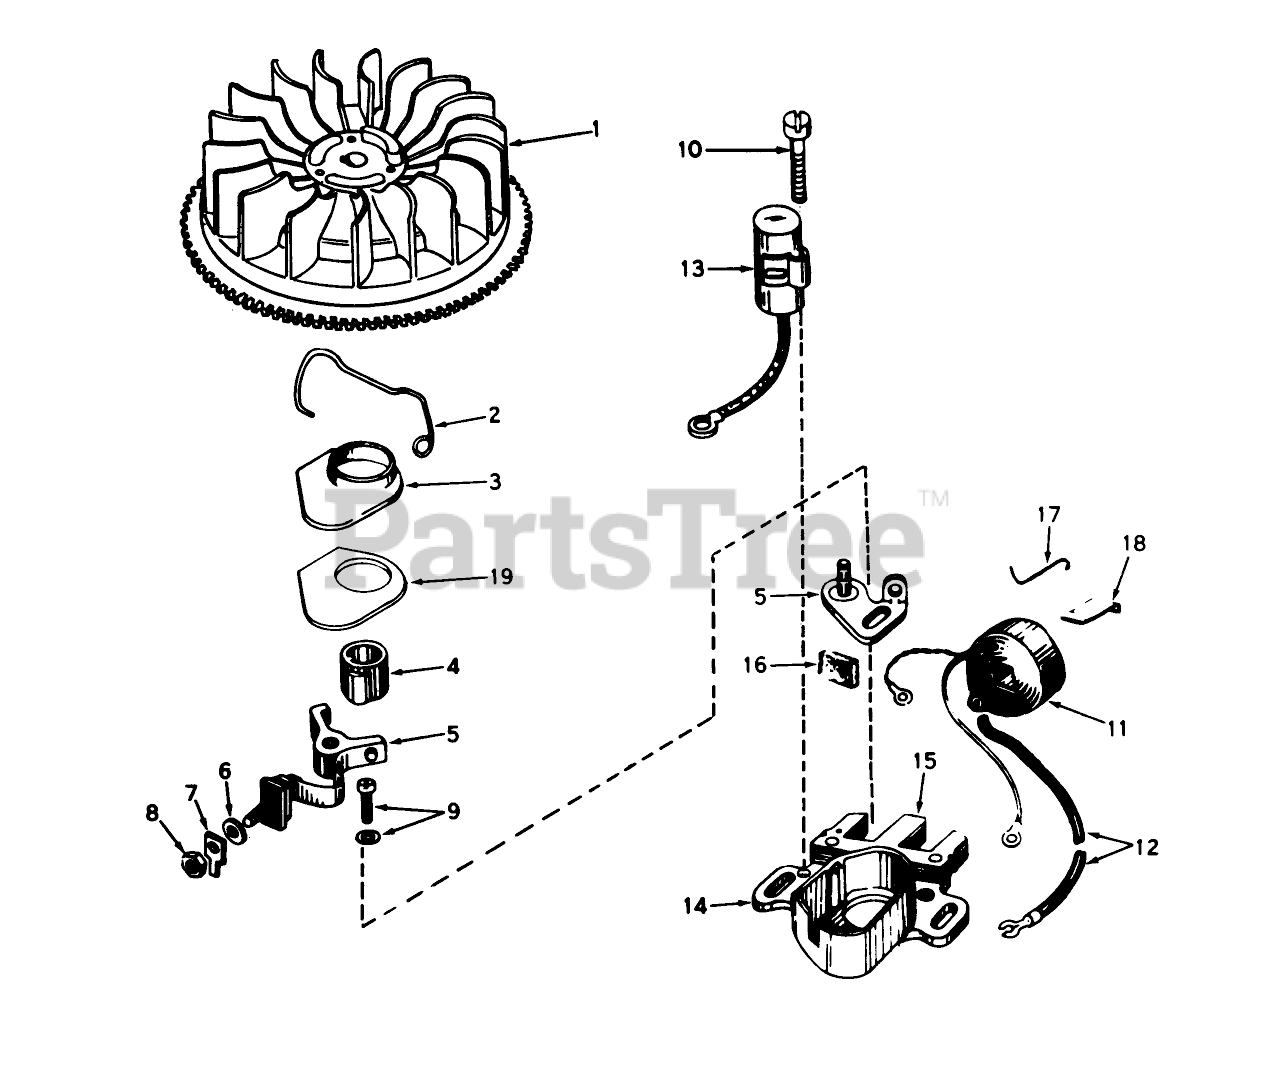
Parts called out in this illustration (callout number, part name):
1	Flywheel
2	Spring Breaker Box
3	Cover, Dust
4	Cam-Breaker
5	Breaker Assy.
6	Washer
7	Terminal
8	DECAL
9	Breaker Screw
10	Condenser Screw
11	Coil Assy. (Incl. No. 12)
12	Wire, Lead
13	Condenser
14	Core Plate
15	A Stator Assy. (Incl. Nos. 5 thru 14, 16, 17 18)
16	Felt,Cam Wiper
17	Clip, Coil
18	Spring Coil Wedge
19	Gasket Dust Cover
